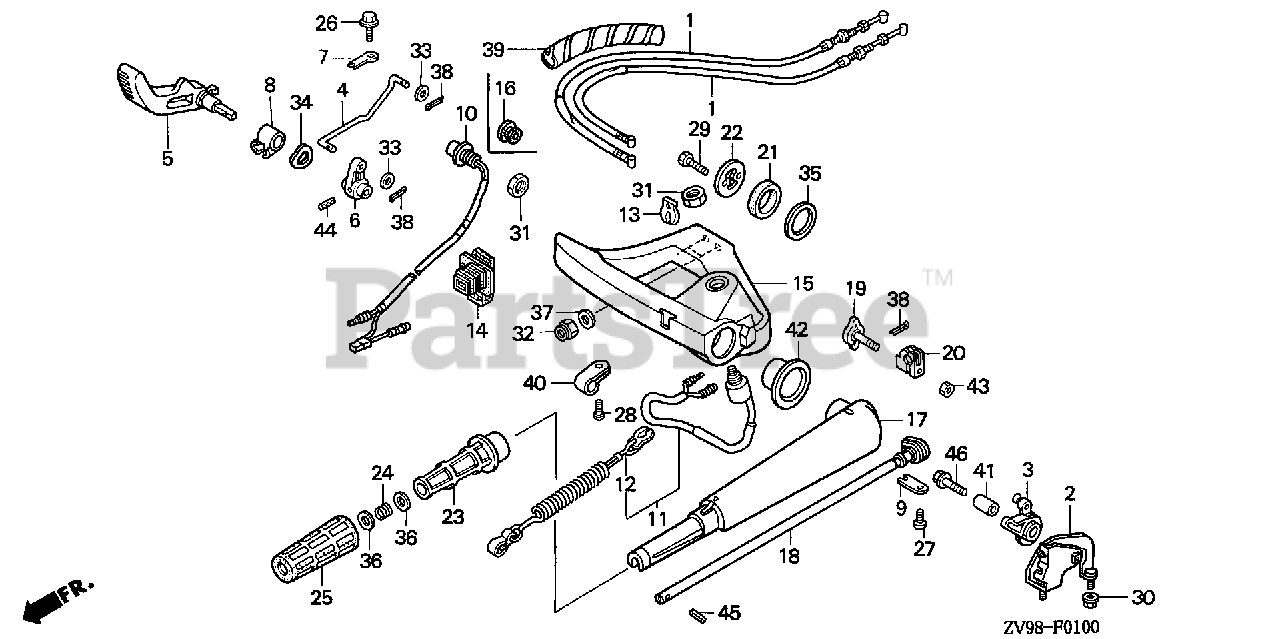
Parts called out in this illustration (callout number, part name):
1	CABLE, THROTTLE
2	BRACKET, THROTTLE CABLE
3	ARM, THROTTLE
5	LEVER, SHIFT
6	LINK, SHIFT (A)
7	PLATE, SHIFT LINK (A)
8	COLLAR, DISTANCE
9	PLATE, SHIFT SHAFT
11	SWITCH ASSY., EMERGENCY STOP
12	WIRE, EMERGENCY
13	CLIP, EMERGENCY LOCK
14	GROMMET, CASE (LOWER) (A)
15	HANDLE, CARRYING *NH282MU* (OYSTER SILVER METALLIC-U)
16	GROMMET, CARRYING HANDLE
17	HANDLEBAR *NH282MU* (OYSTER SILVER METALLIC-U)
18	REEL, THROTTLE
19	BOLT, FRICTION
20	BLOCK, THROTTLE FRICTION
21	RUBBER, HANDLE MOUNTING
22	PLATE, HANDLEBAR
23	PIPE, GRIP
24	SPRING, GRIP PIPE
25	RUBBER, GRIP
26	BOLT, FLANGE (6X12)
27	SCREW, PAN (6X8)
28	SCREW, PAN (5X12)
29	BOLT, HEX. (6X16)
30	NUT, SELF-LOCK (6MM)
31	NUT, HEX. (16MM)
32	NUT, SELF-LOCK (10MM)
33	WASHER, PLAIN (5MM)
34	WASHER, WAVE (14MM)
35	WASHER, HANDLEBAR (36MM)
36	WASHER (10MM)
37	WASHER, PLAIN (10MM)
38	PIN, SPLIT (2.0)
39	TUBE, SPIRAL
40	CLIP, WIRE HARNESS (6.3MM)
41	COLLAR, DISTANCE (6.5X10.5X16)
42	COLLAR, HANDLEBAR
43	NUT, HEX. (6MM)
44	PIN, SPRING (4X20)
45	PIN, SPRING (4X28)
46	BOLT, FLANGE (6X28)
